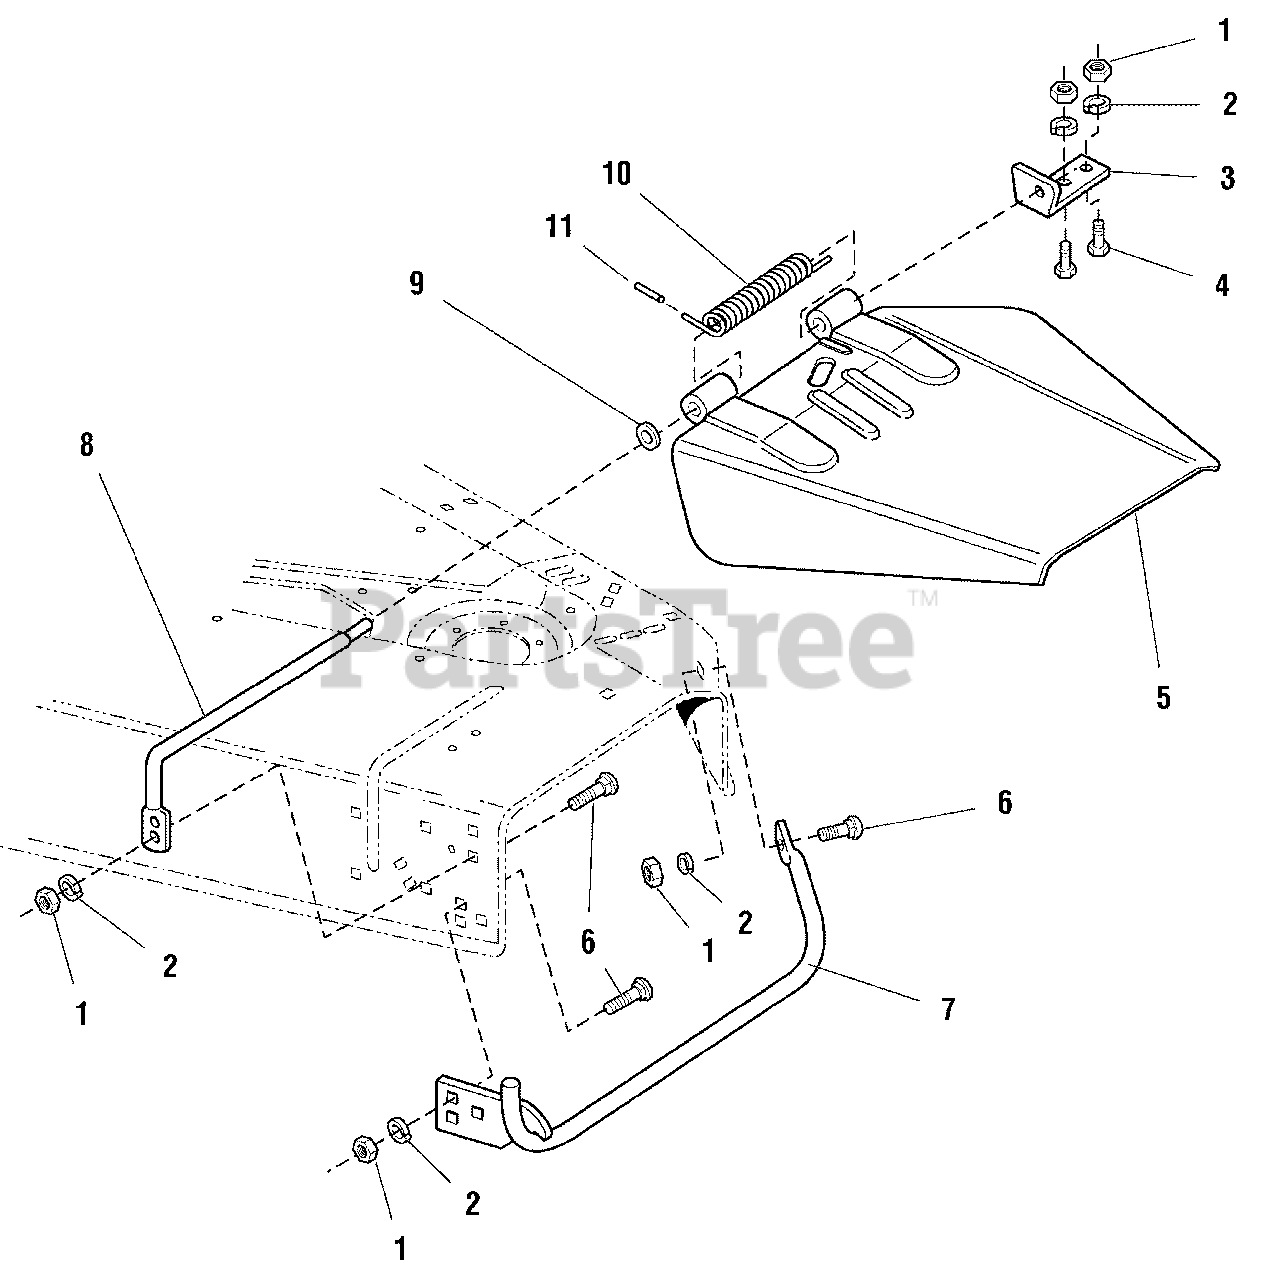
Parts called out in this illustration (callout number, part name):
1	NUT, Hex, 3/8-16
2	LOCKWASHER, 3/8
3	BRACKET
4	CAPSCREW, Hex Head, 3/8-16 x 1
5	DEFLECTOR ASSEMBLY
6	CARRIAGE BOLT, 3/8-16 x 1
7	STONE GUARD
9	WASHER, 5/8
10	SPRING, Torsion
11	CAP, Spring End
